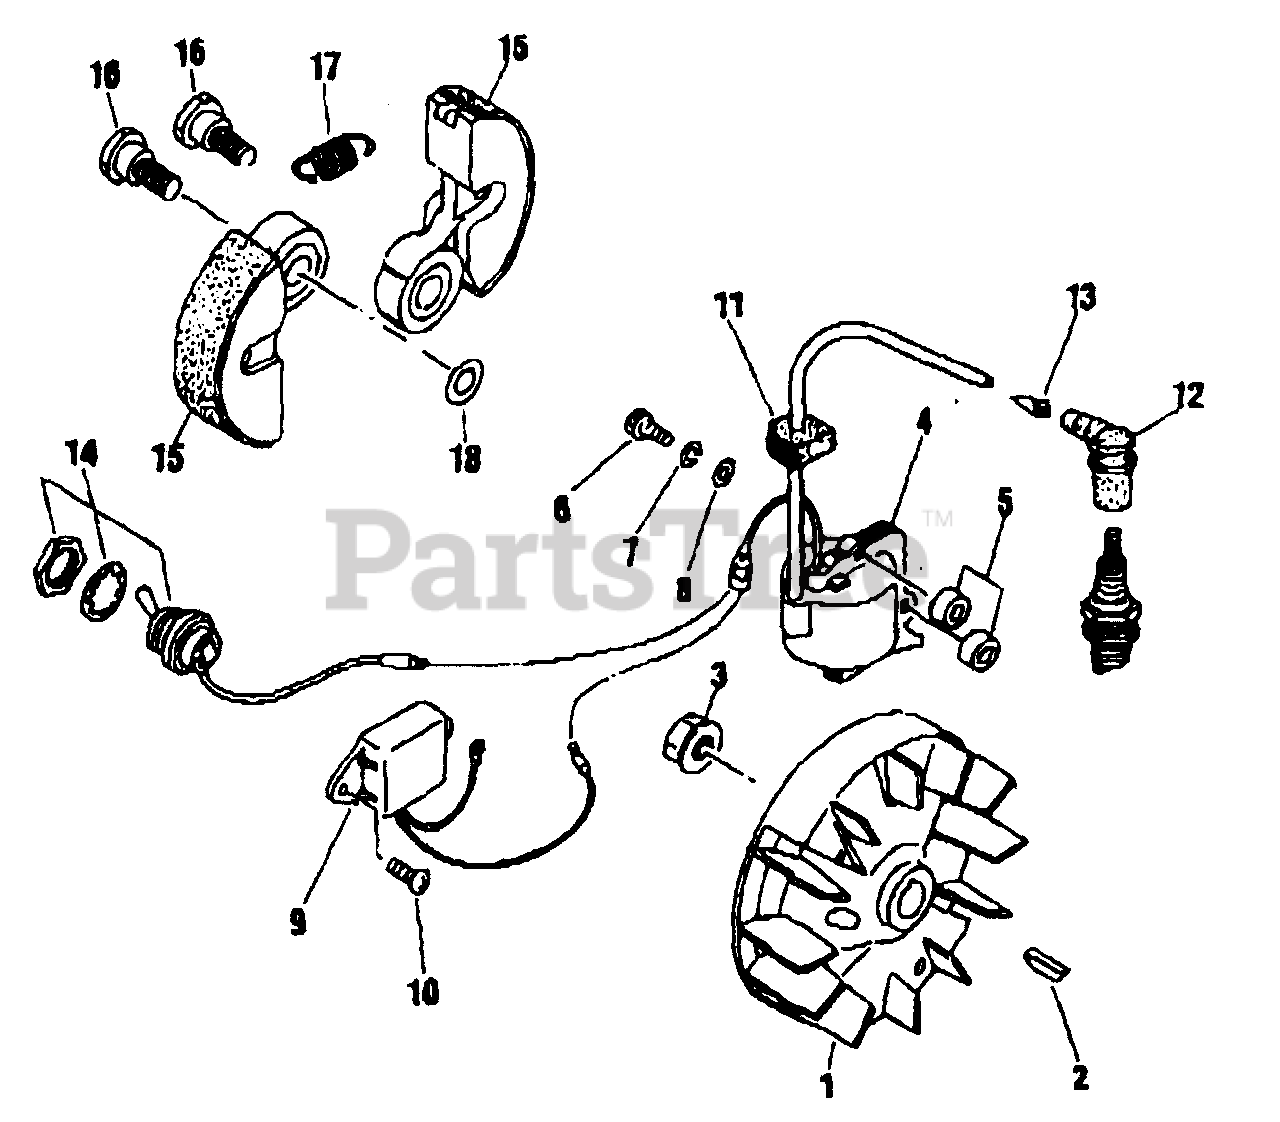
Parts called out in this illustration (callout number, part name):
1	ROTOR
2	KEY - 3X10
3	NUT - 8
4	COIL, IGNITION
5	INSULATOR
6	SCREW - 4X26
7	LOCKWASHER - 4
8	WASHER
9	UNIT
11	GROMMET
12	CAP, SPARK PLUG
13	TERMINAL, SPARK PLUG CAP
16	BOLT, CLUTCH
17	SPRING, CLUTCH
18	WASHER - 6
